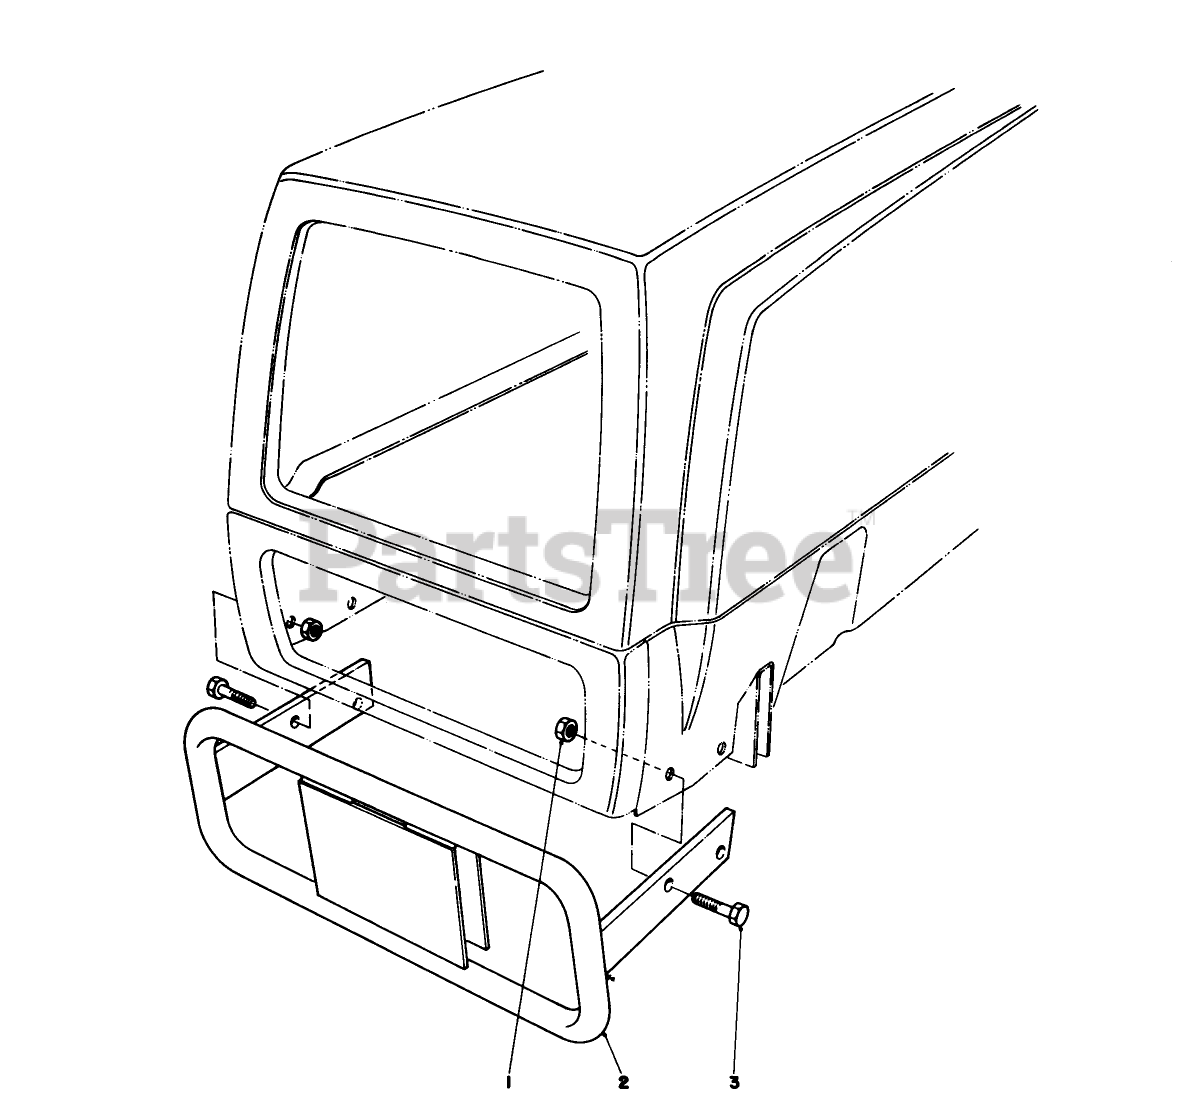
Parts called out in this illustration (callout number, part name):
1	NUT-LOCK, CONE
2	Bumper W.A.
3	SCREW-HH
